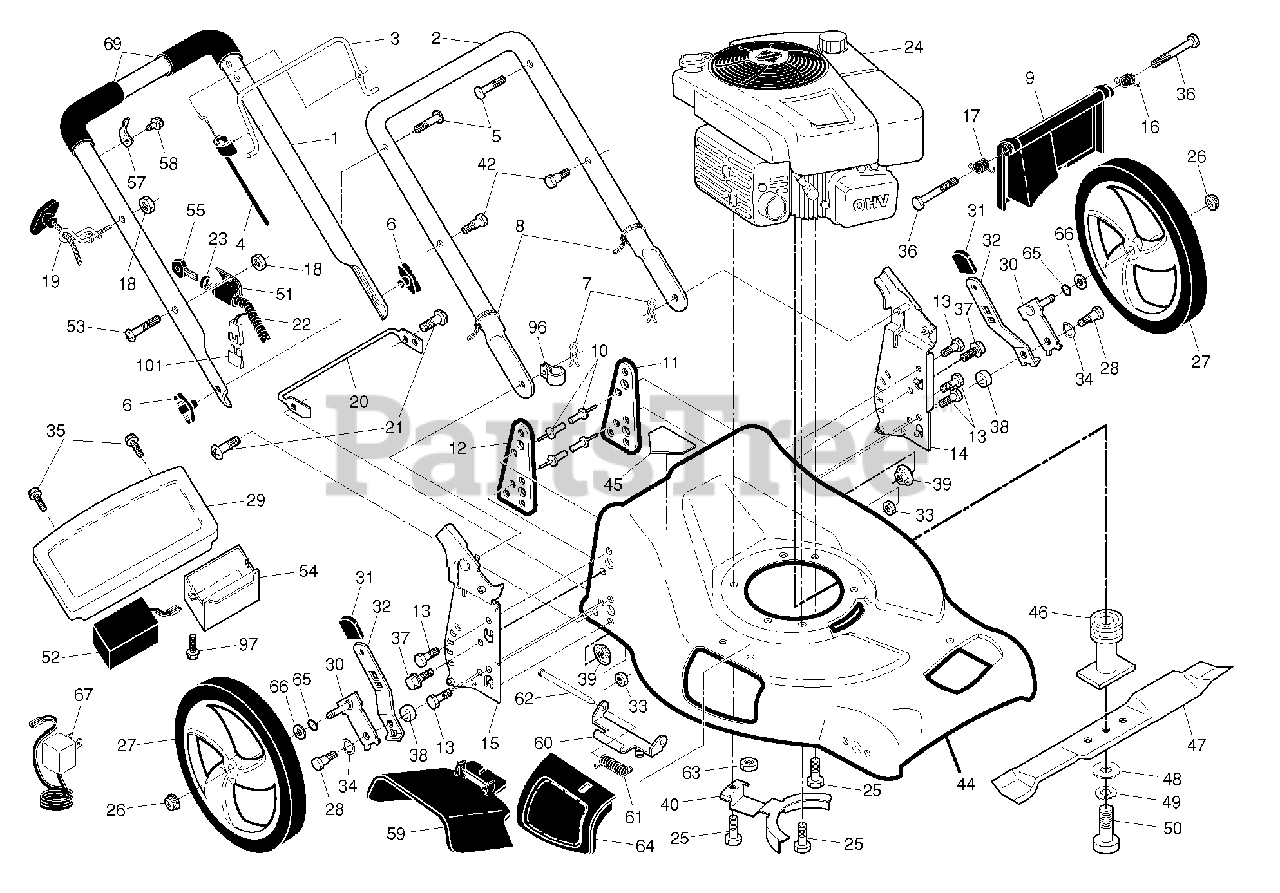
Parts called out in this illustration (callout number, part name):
2	HANDLE.LOWER.21FGD.ES.NB.BLACK
4	CABLE.ASM.ZONE.CONTROL
5	BOLT, HANDLE 5/16-18X1.75
6	KNOB, DEFLECTOR
7	HAIRPIN COTTER
8	TIE GUIDE
9	REAR DOOR ASSEMBLY
10	RIVET BLIND
11	SUPPORT BRACKET LH
12	BRACKET.SUPRT.RH.21.FWGD
13	SCREW 14-20 X 5/8
15	BRACKET.ASM.HNDL.RT.21.FGD.HW
16	SPRING.REAR.DOOR.EZ.21.LT
17	SPRING.REAR.DOOR.EZ.21.RT
18	NUT
19	GUIDE.ROPE.STD.BLK.ZIN
21	SCREW
22	WIRING HARNESS
23	NUT.CAP.SNAP-ON.KEY START
25	BOLT 3/8-16X1-1/8
26	NUT.HEX.FLANGE.3/8-16.LOCKNUT
28	SHOULDER BOLT 5/16-18
29	PANEL.TRIM.21.FWGD.ES
30	ARM.ASM.AXLE.REAR.5/9.POS.BZP
31	SELECTOR KNOB
32	SELECTOR SPRING
33	NUT.71038.31-18.HEX.NYLOCK
34	WASHER FLAT
35	SCREW.PAN.HEAD.#10
37	BOLT
38	SPACER.HEIGHT.ADJUSTER
39	NUT.FLANGE.5/16
40	BRACKET.ENG/BELTKEEPER
42	SCREW.SHOULDER.HH.10X.281X.6
45	DECAL.INTERNATIONL.CUTFINGER
47	BLADE.21.PUSH
48	WASHER,HARDEN
49	LOCKWASHER
50	SCREW, HEX HD 3/8-24 X 1-3/8
51	HOUSING.WIRING.HARNESS
52	BATTERY.AMP.CONNECTOR
53	SCREW.(COMBINATION CONTROL)
54	BOX.BATTERY.TRIM
55	KEY.MOLDED
57	BRACKET.UPSTOP.RT
59	DISCHARGE DEFLECTOR
60	HINGE BRACKET ASSEMBLY
61	SPRING.TORSION
62	ROD.HINGE.21
63	LOCKNUT
64	DOOR.MULCH.21.REAR
65	O-RING..070X.487.NEOPRENE
66	WASHER PM
69	GRIP.HANDLE.FOAM.WIDE.(1 SIDE)
96	CLIP.CABLE.BLK
101	FUSE, 40A
